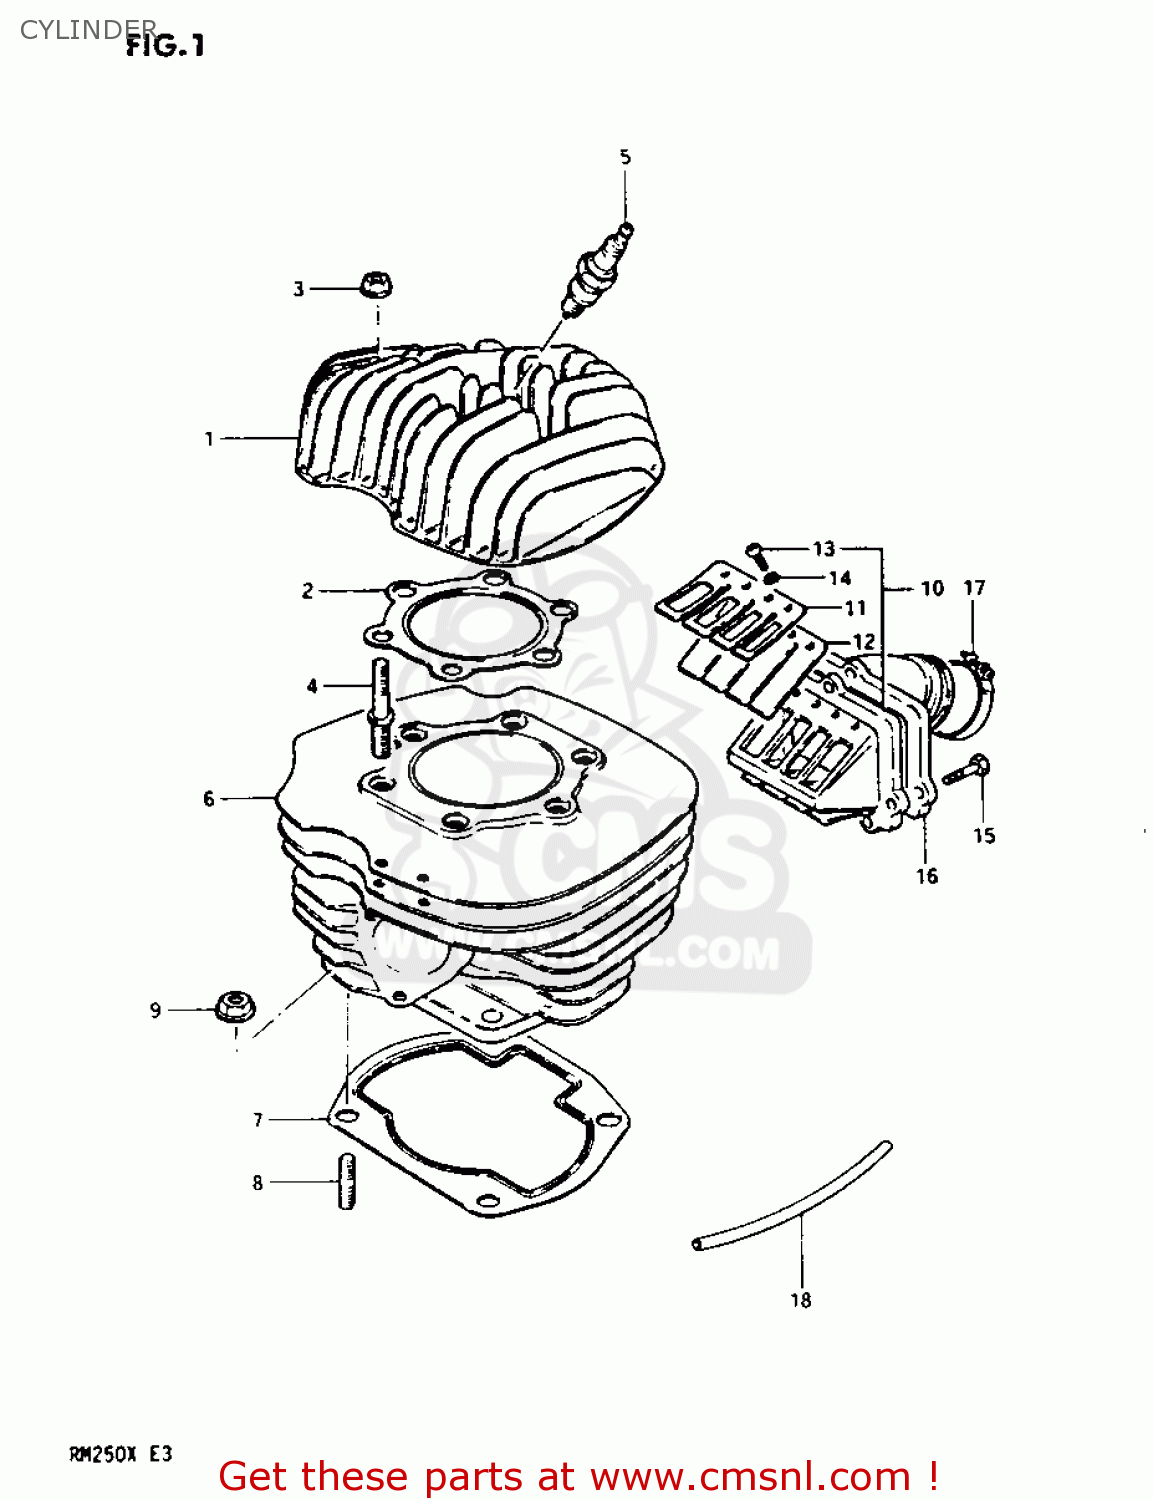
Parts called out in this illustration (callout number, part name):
1	HEAD,CYLINDER
2	GASKET,CYLINDER HEAD (NAS)
3	NUT
4	BOLT,STUD
5	SPARK PLUG N-2G CHMP
6	CYLINDER
7	GASKET,CYLINDER (MCA)
8	STUD 10X30
9	NUT
10	VALVE ASSEMBLY,REED
11	STOPPER,REED VALVE
12	VALVE,REED
13	SCREW
14	LOCK WASHER
15	BOLT
16	PIPE,INTAKE
17	CLAMP
18	HOSE(4X7X600)
